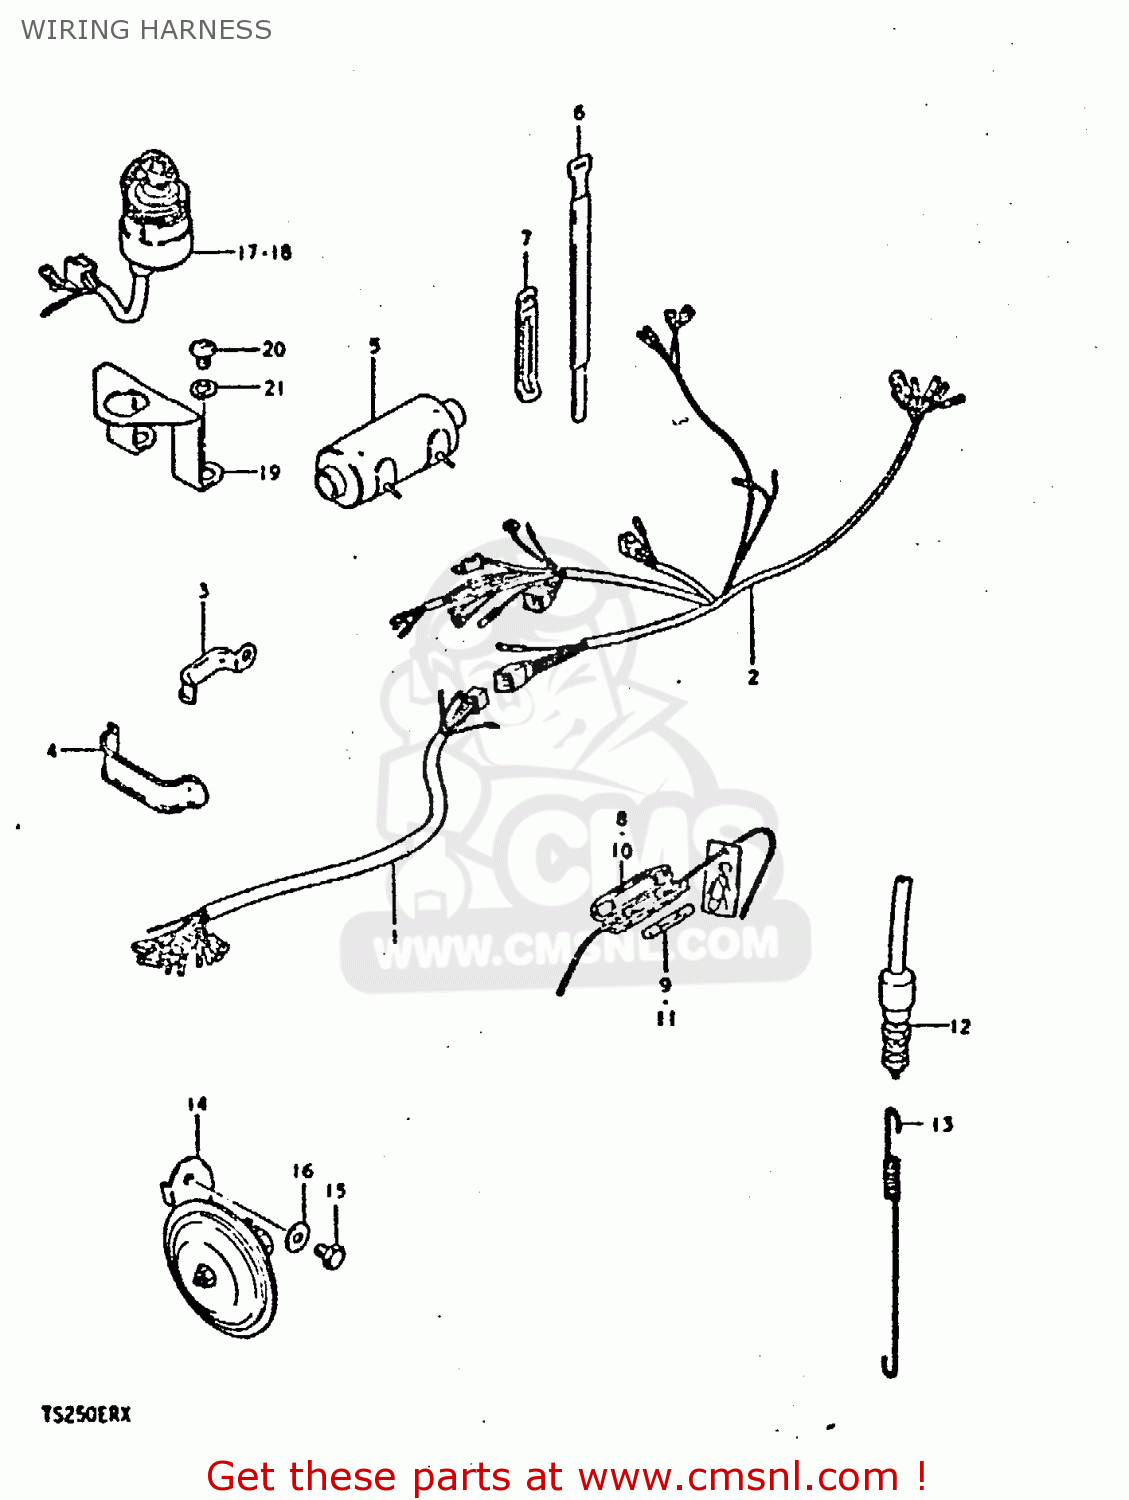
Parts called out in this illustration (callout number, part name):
1	HARNESS,WIRING NO.1
2	WIRING HARNESS NO.2
3	CLAMP
4	CLAMP
5	BOOT,WIRING HARNESS
6	CLAMP
7	CLAMP L:35
8	BOX ASSEMBLY,FUSE
9	FUSE(15A)
12	SWITCH ASSEMBLY,STOP LAMP
13	SPRING
14	HORN ASSEMBLY
15	BOLT
16	WASHER
18	SWITCH ASSY, IGNITION
19	BRACKET,IGNITION SWITCH
20	SCREW
21	LOCK WASHER
